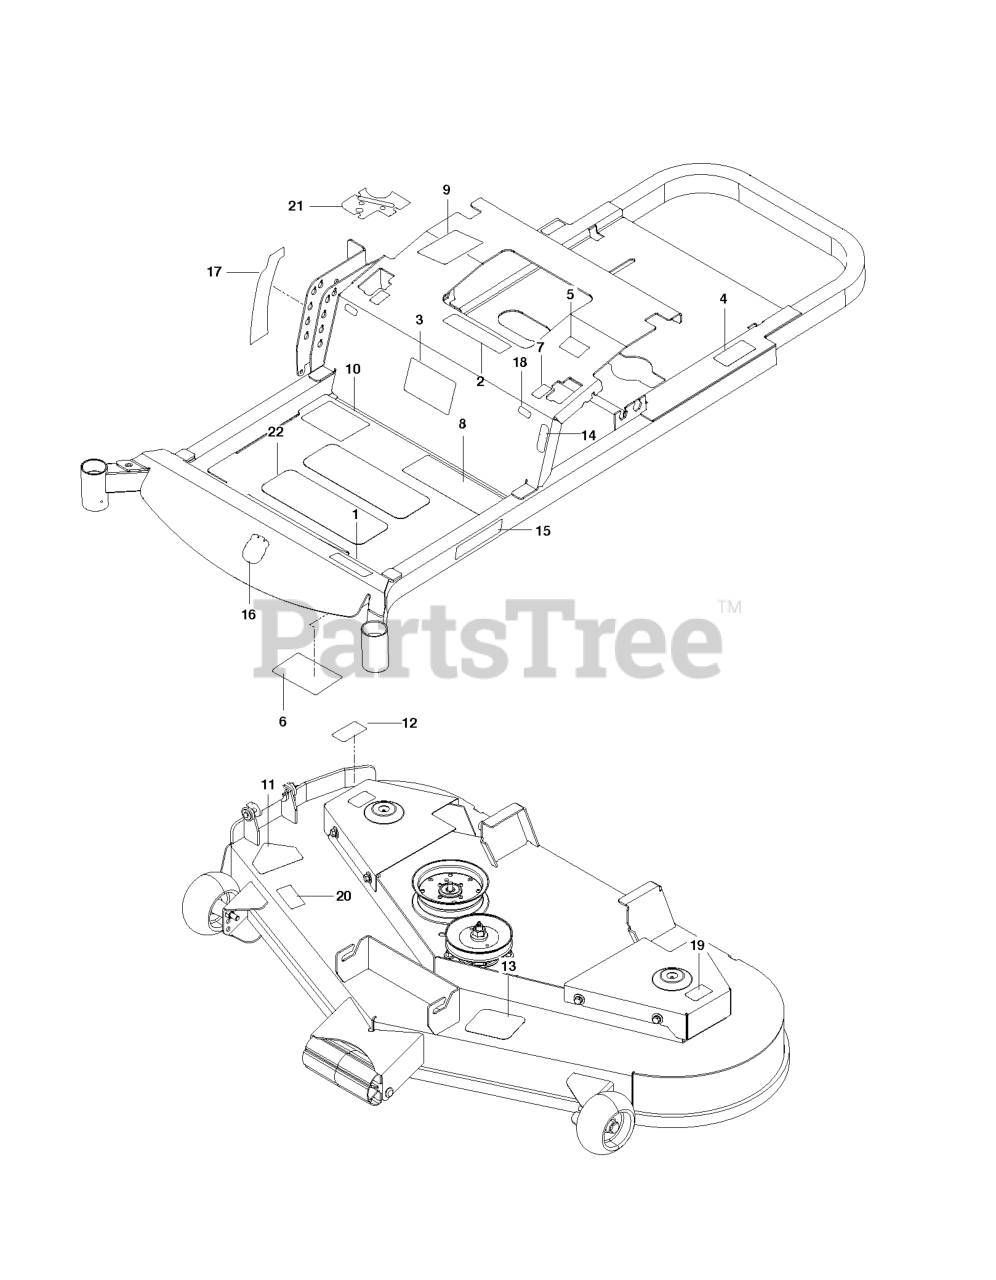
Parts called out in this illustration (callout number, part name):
1	DECAL RZ4824F
2	EURO DECAL-BATTERY WARNIN6
3	DECAL, START
4	DECAL, DO NOT TOW
5	DECAL, EXITING MOWER
6	DECAL, SERVICE
7	DECAL, MOTION CONTROL
8	DECAL, SAFETY WARNING
9	DECAL, CUSTOMER RESPNSIBILITY
10	DECAL, WARNING
11	DECAL, CPSC
12	DECAL, CAUTION
13	DECAL, BELT ROUTING
14	DECAL, PARK BRAKE
15	RP.DECAL.BADGE.170MM.TEXTLOGO
16	DECAL.AUGER.HUSQ.CROWN.SNOW
17	DECAL, DECK HEIGHT, HUSQ
18	DECAL, F.S.T.
19	DECAL, NO STEP
20	DECAL, EURO SEVERING
21	DECAL, CTRL PANEL, HUSQ
22	ANTI-SKID PAD
